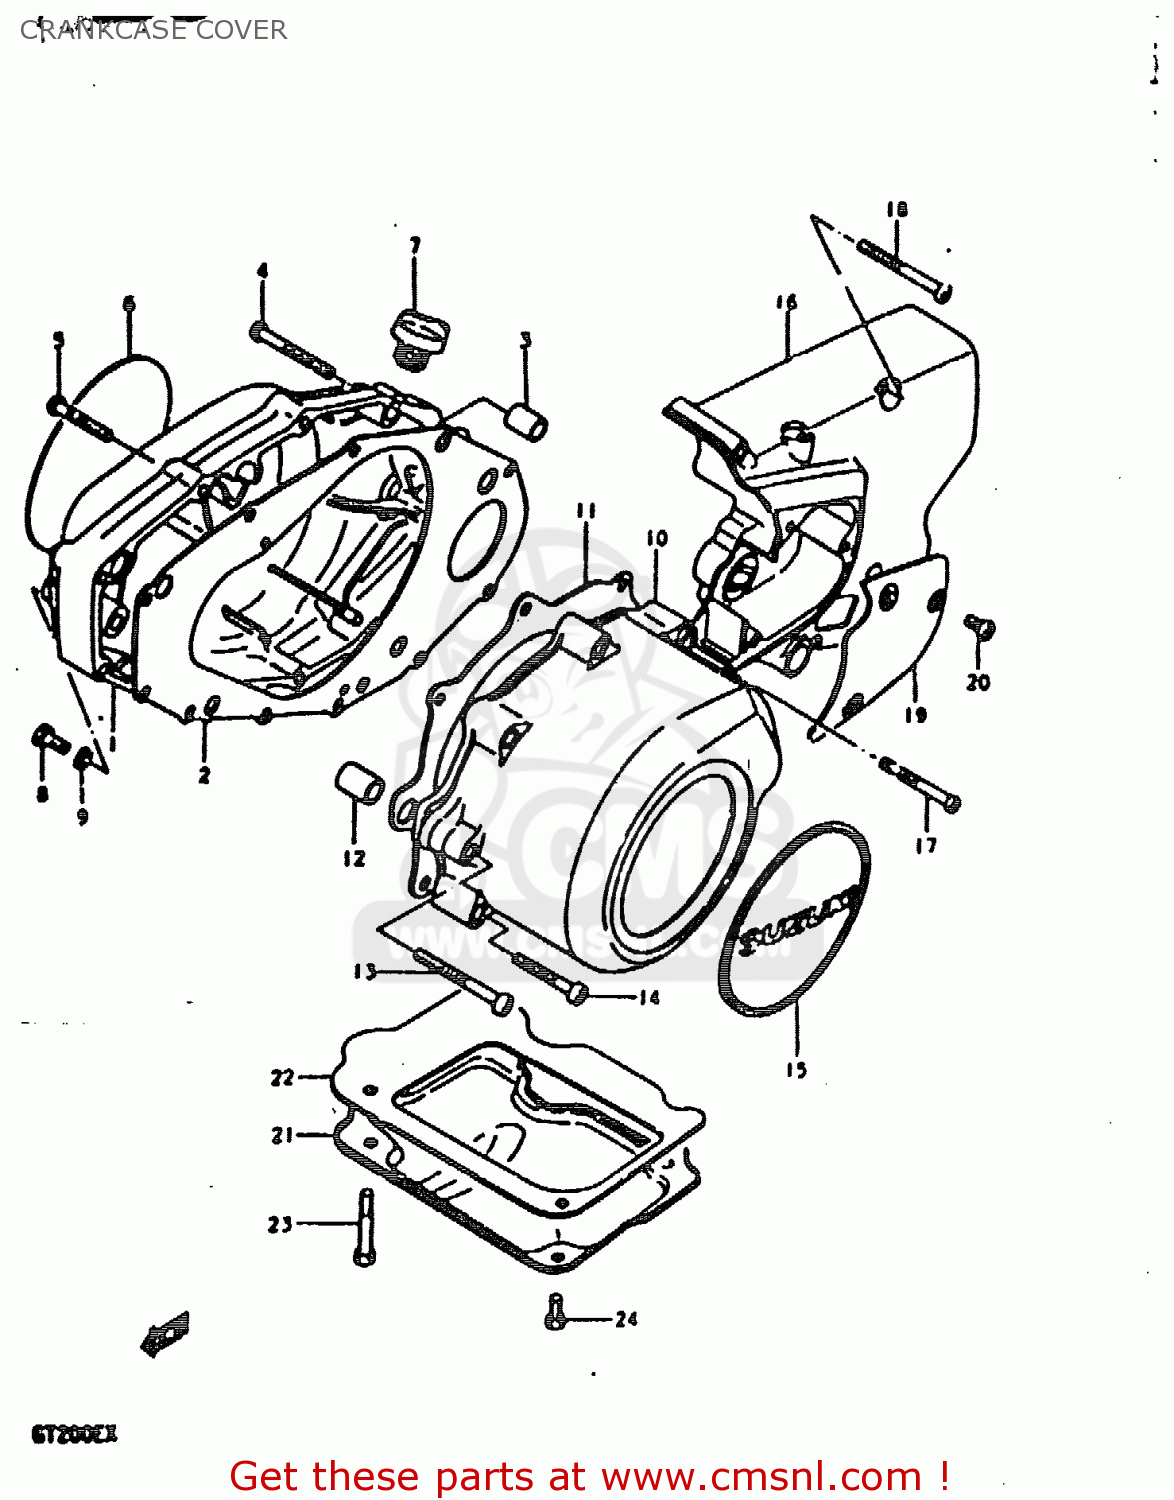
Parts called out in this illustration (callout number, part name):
1	COVER, CLUTCH
2	GASKET, CLUTCH COVER (MCA)
3	PIN
4	SCREW
5	SCREW (6X35)
6	EMBLEM,COVER
7	PLUG
8	SCREW(6X10)
9	GASKET(6.2X11X1) (NAS)
10	COVER, MAGNETO
11	GASKET (MCA)
12	PIN
13	SCREW
14	SCREW (6X35)
15	EMBLEM,COVER
16	COVER, ENGINE SPROCKET
17	SCREW (6X45)
18	SCREW
19	CAP, RELEASE ADJUSTO
20	SCREW
21	COVER,STARTER MOTOR
22	GASKET,STARTER (MCA)
23	BOLT
24	BOLT(6X8)
